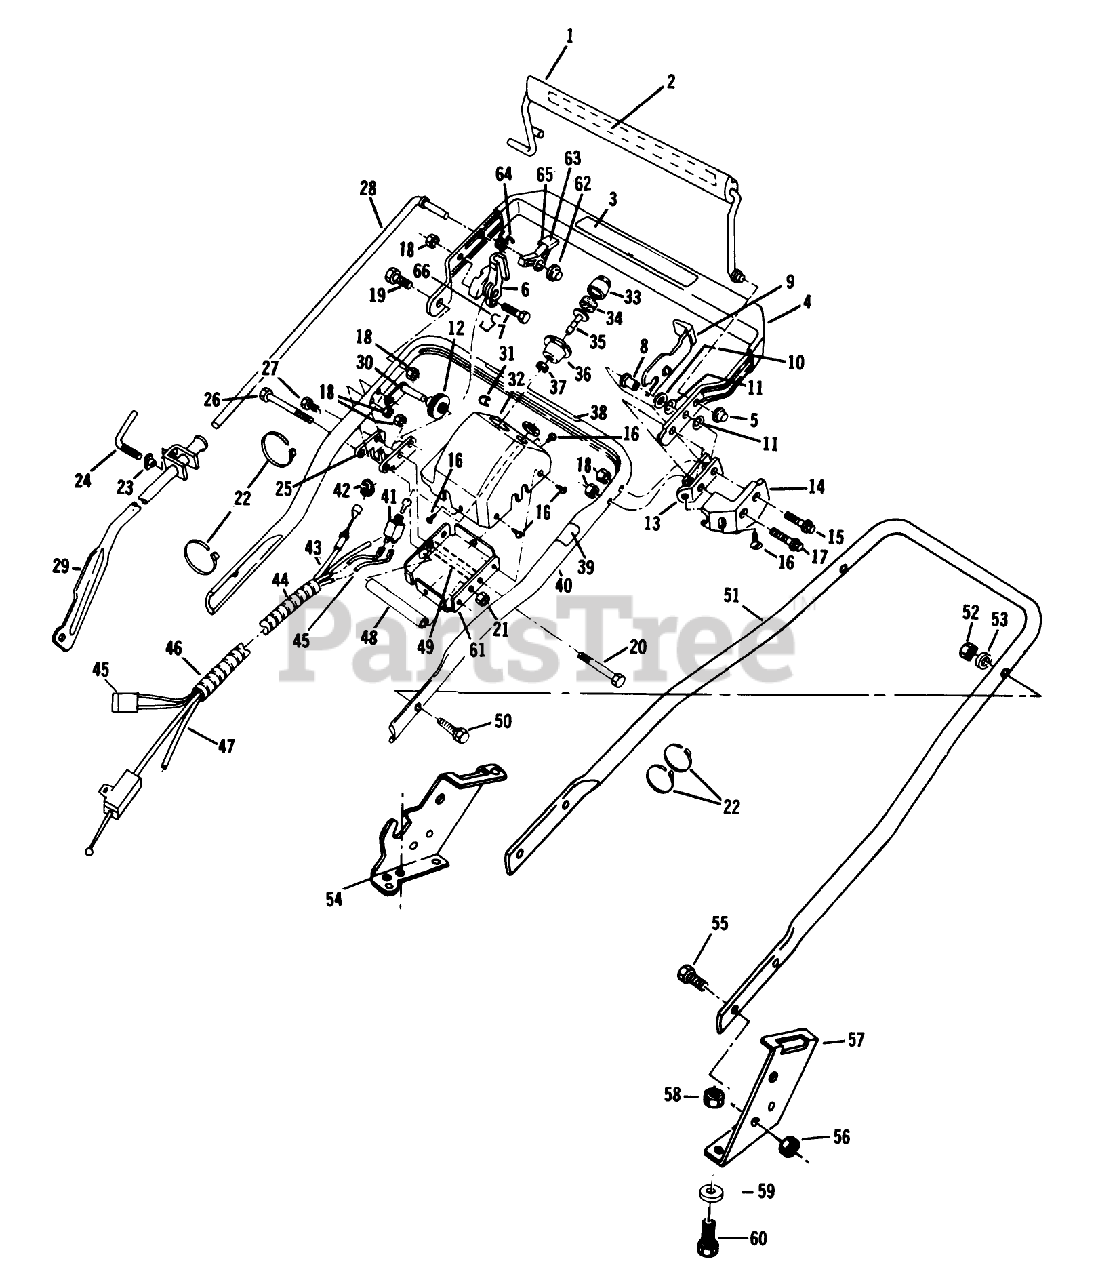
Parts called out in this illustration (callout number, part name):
8	SPACER
10	WASHER M
13	DOWN STOP
14	LOCKOUT GUARD
15	BOLT SHOU
16	SCREW F
17	SCREW
18	LOCKNUT E
19	BOLT
26	BOLT-CONSOLE
34	FILTER S
37	LOCKNUT S
39	PULLEY UPPER PL
41	SWITCH AY
42	RET. RING
43	CONTROL CABLE
49	SPACER
52	NUT-LOCK F
53	WASHER-CURVED
55	BOLT
56	NUT-JAM, LOCKING
58	NUT-LOCK F
59	WASHER
